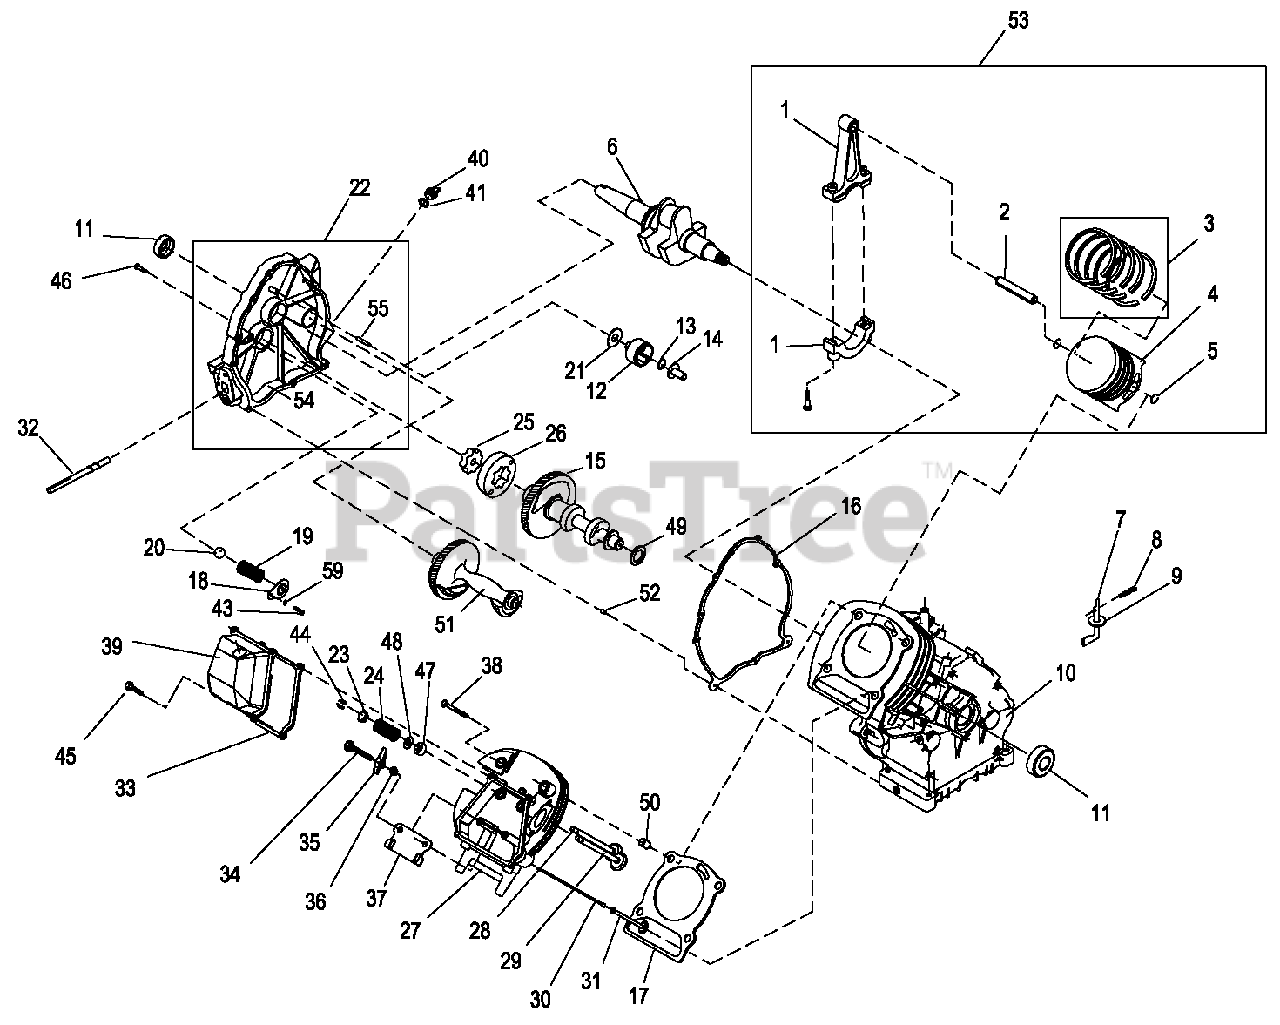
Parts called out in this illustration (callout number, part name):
1	ASSEMBLY, CONNECTING ROD
2	PIN, PISTON D20
3	RING SET, PISTON dia90
4	PISTON FLAT TOP 90 HSB 2013
5	RETAINER, PISTON PIN 20
6	CRANKSHAFT SAE PTO TAPER LF
7	ARM, GOVERNOR RC45
8	PIN COTTER "R" .059 X 1/4 X 1-1/8
9	WASHER, GOVERNOR ARM THRUST
10	CRANKCASE, SUBASSEMBLY WITH PLUGS GH410
11	SEAL, 35 I.D. CRANKSHAFT
12	ASSEMBLY, GOVERNOR GEAR
13	C-RING, GOVERNOR GEAR RETAINER
14	SPOOL, GOVERNOR- MACHINE
15	CAMSHAFT ASSEMBLY
16	GASKET , CRANKCASE
17	GASKET, HEAD 410
18	COVER, OIL PRESSURE RELIEF
19	SPRING, OIL RELIEF 360
20	BALL, DIA 11/32 PRESSURE RELIEF
21	WASHER, THRUST GOVERNOR GEAR
22	ASSEMBLY, COVER
23	RETAINER, VALVE SPRING
24	VALVE SPRING
25	GEROTOR, INNER 12 THK
26	GEROTOR, OUTER 12 THK
27	ASSEMBLY,CYLINDER HEAD SEATS & GUIDES
28	VALVE, EXHAUST
29	VALVE, INTAKE
30	PUSH ROD 174.9
31	TAPPET
32	ASSEMBLY, SCREEN OIL PICK-UP
33	GASKET, ROCKER COVER 410
34	STUD, D20 PIVOT BALL
35	ROCKER ARM
36	NUT, JAM M8 (ROCKER ARM)
37	PLATE, PUSH ROD GUIDE
38	SCREW, HHFL M10-1.5 X 105
39	ASSEMBLY, ROCKER COVER OHVI
40	PLUG, OIL FILL PLASTIC ORANGE
41	O-RING 11/16 - 7/8
43	SCREW HHC M5-0.8 X 10 C8.8
44	KEEPER, VALVE SPRING
45	SCREW HHFCS M6-1 X 12 G8.8
46	SCREW, HHFC M8-1.25 X 42
47	SEAL, VALVE STEM D7
48	WASHER, VALVE SPRING
49	WASHER, LARGE WAVE
50	SLEEVE, DOWEL PIN 14 DIA.
51	BALANCER
52	SLEEVE, DOWEL PIN 12 DIA.
53	ASSY PISTON FLAT TOP GT999
54	GEARCOVER, MACHINED
55	SHAFT, GOVERNOR
56	PLUG, 6.5 DIA.
57	PLUG, 8.4 DIA.
58	SHAFT, BEARING TUBE
59	WASHER, LOCK M5
